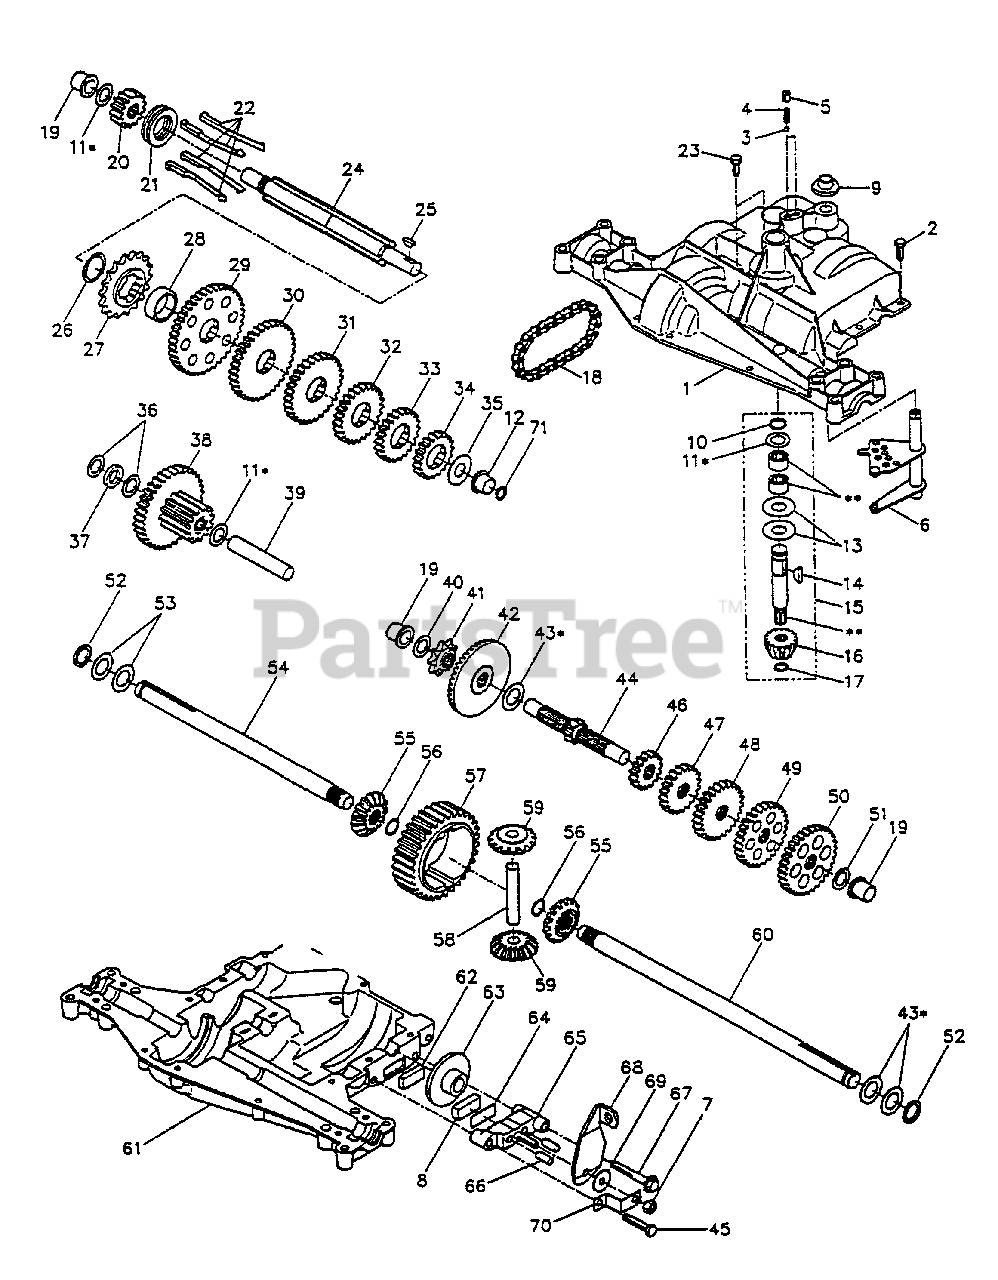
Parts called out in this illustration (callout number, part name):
1	Housing, Upper
2	Screw, Self-Tapping, Large 1/4-20 x .734
3	Ball, Detent
4	Spring, Detent
5	Screw, Set
6	Kit, Shifter Assembly
7	Locknut 5/16-24
8	Puck, Friction
9	Boot, Shifter
10	Ring, Retaining
11	Assembly, Kit, Shim .625 Shaft
12	Bearing, Flange
13	Washer, Plain .632 x 1.38 x .046
14	Key, Woodruff, #9
15	Assembly, Kit, Input Shaft
16	Pinion, Bevel, 14 Teeth
17	Ring, Retaining
18	Chain, 24 Pitches
19	Bearing, Flange
20	Gear, Spur, 14 Teeth
21	Collar, Clutch
22	Assembly, Kit, Clutch Keys
23	Screw, Self-Tapping, with Sealer
24	Shaft, Intermediate
25	Key, Woodruff, #61
26	Ring, Retaining
27	Sprocket, 18 Teeth
29	Gear, Spur, 40 Teeth
30	Gear, Spur, 35 Teeth
31	Gear, Spur, 30 Teeth
32	Gear, Spur, 25 Teeth
33	Gear, Spur, 92 Teeth
34	Gear, Spur, 19 Teeth
35	Washer, Plain .640 x 1.37 x .061
36	Washer, Plain .632 x 1.00 x .026
37	Spacer .630 x 1.00 x .169
38	Assembly, Gear, Combination of 12 Teeth and 35 Teeth
39	Shaft, Idler
40	Washer, Plain .631 x 1.00 x .015
41	Sprocket, 9 Teeth
42	Gear, Bevel, 42 Teeth
43	Assembly, Kit, Shim .750 Shaft
44	Shaft, Drive
45	Screw, Self-Tapping, Large 5/16-18 x 1.44
46	Gear, Spur, 15 Teeth
47	Gear, Spur, 20 Teeth
48	Gear, Spur, 25 Teeth
49	Gear, Spur, 28 Teeth
50	Gear, Spur, 31 Teeth
51	Washer, Plain .632 x 1.00 x .060
52	Washer, Neoprene
53	Washer, Plain .758 x 1.25 x .031
54	Axle, L.H.
55	Gear, Miter, 15 Teeth
56	Ring, Retaining
57	Gear, Spur, 32 Teeth
58	Shaft, Cross
59	Gear, Miter, 15 Teeth
60	Axle, R.H.
61	Housing, Lower
62	Puck, Friction
63	Disc, Brake
65	Jaw, Brake
66	Pin, Dowel
67	Screw, Self-Tapping, Large 5/16-18 x 2.25
68	Lever, Actuating
69	Washer, Plain .321 x 1.00 x .055
70	Bracket, Anti-Rotation
71	Square Ring
72	Grease
